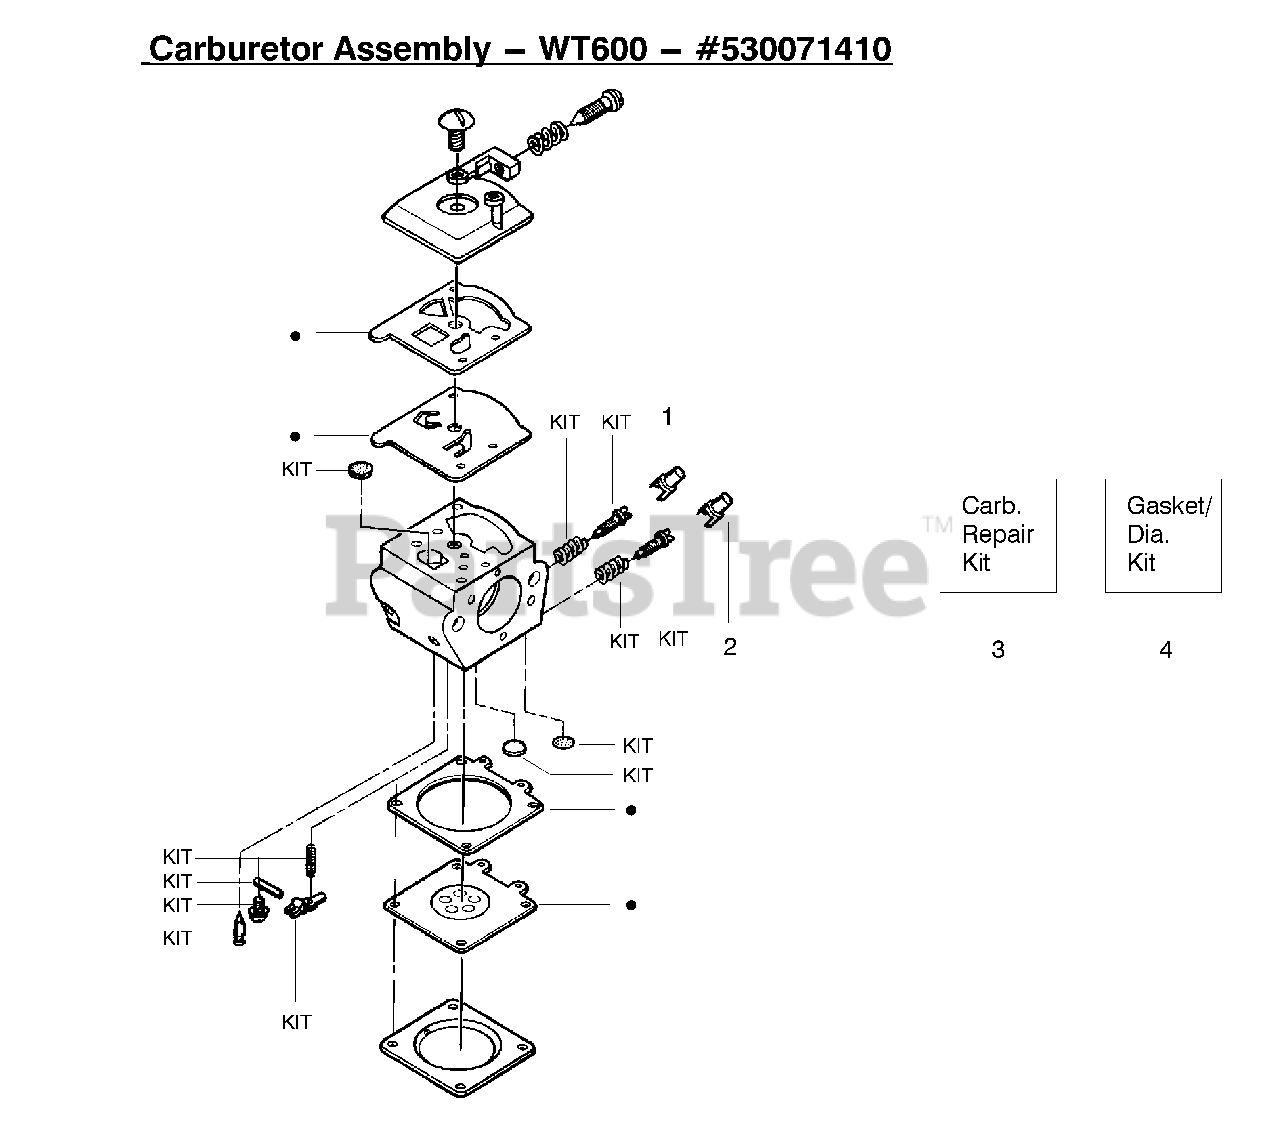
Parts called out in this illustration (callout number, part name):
1	Limiter Cap-High
2	Limiter Cap-Low
3	Carburetor Repair Kit
4	Gasket Diaphragm Kit
